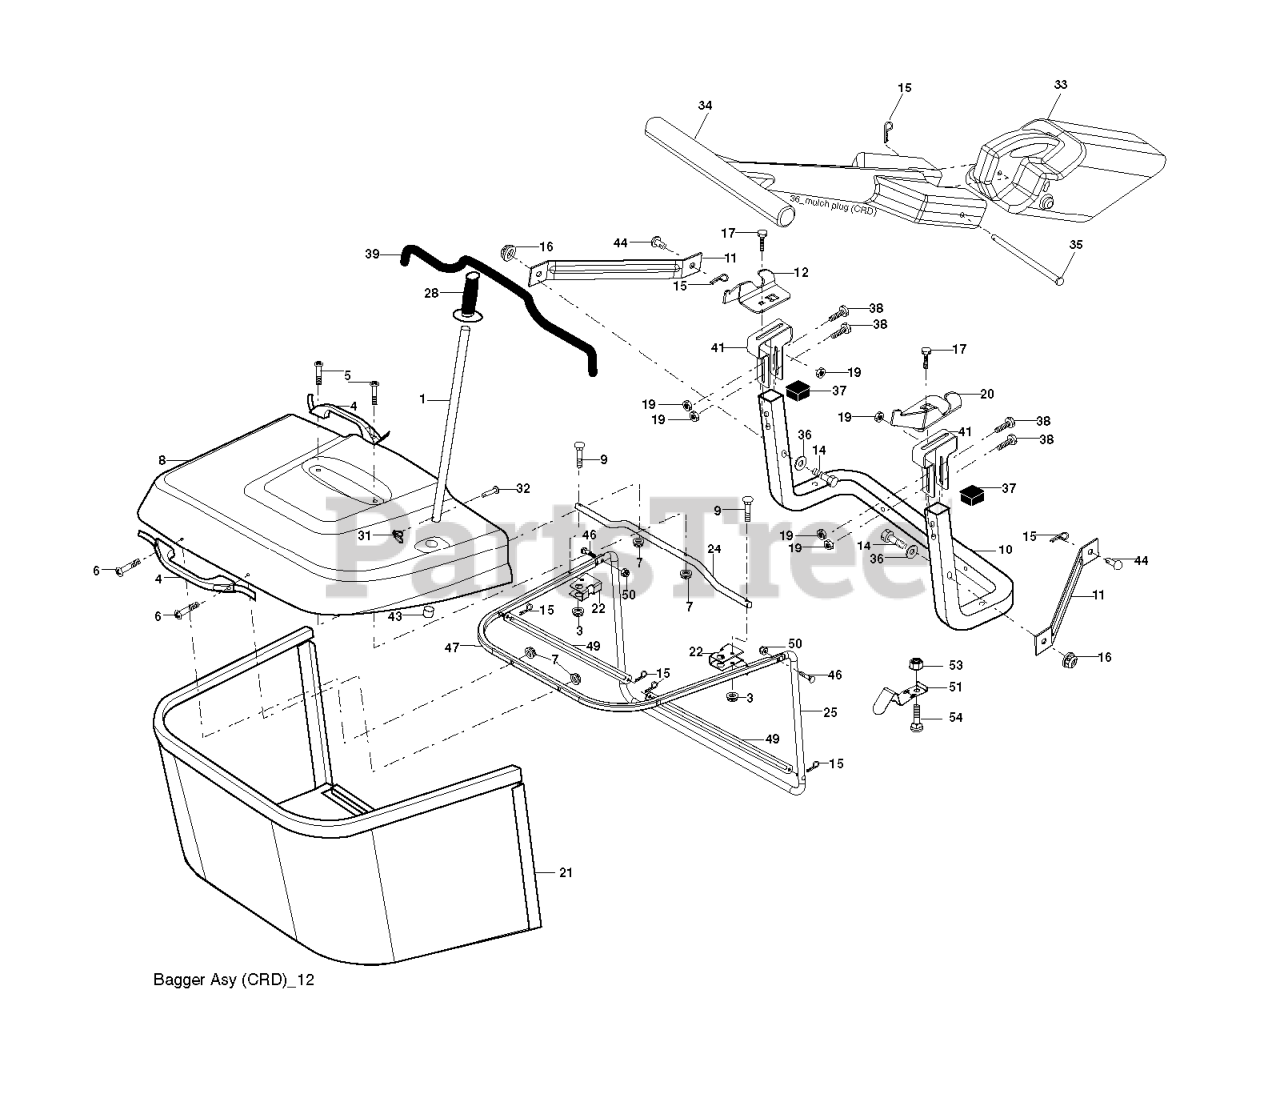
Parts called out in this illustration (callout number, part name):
1	TUBE HANDLE
3	NUT T
4	HANDLE.BAGGER.W/LVRS.BLK.CRD
5	SCREW.PAN.HEAD
6	REPL BY 532 75 00-29
8	COVER.PNT.BGR.CRD.WSLOTS.MS668
9	Bolt Carriage 1/4-20 x 2.25d x Gr.5
10	TUBE
11	BRACKET.SUPPORT.UPPER.BAG.CRD
12	BRKT PIVOT
14	BOLT-HEX EAK
15	RETAINER-SPRNG RB
16	NUT LOCK FLG 3/8-16 UNC
17	RP BOLT 5/16-18 X3/4 ZN/YEL GR
19	NUT LOCK HEX FLANGE 5/16-18
20	BRKT.PIVOT.RH.CRD
21	BAGGER.ASM.CRD.2007
22	BRKT.SIDE.BAG.CRD
24	TUBE.PIVOT.BAG.CRD.BLACK
25	PIPE
28	GRIP.HANDLE.BLACK
31	RETAINER CLIP
32	RIVET,DRILLED
33	MULCH PLUG, CTH150
34	HANDLE.MULCHER.92.CRD (2 2)
36	WASHER
37	Plug Support Bagger CRD
38	BOLT.5/16-18X2.5
39	SEAL.TRIM.37'
41	BRKT.VERT.ADJ.BAGGER.CRD
43	PLUG, TUBING END
46	BOLT.CARRIAGE.5/16-18
47	PIPE
49	ROD
50	NUT.71038.31-18.HEX.NYLOCK
51	LATCH
53	NUT
54	BOLT
